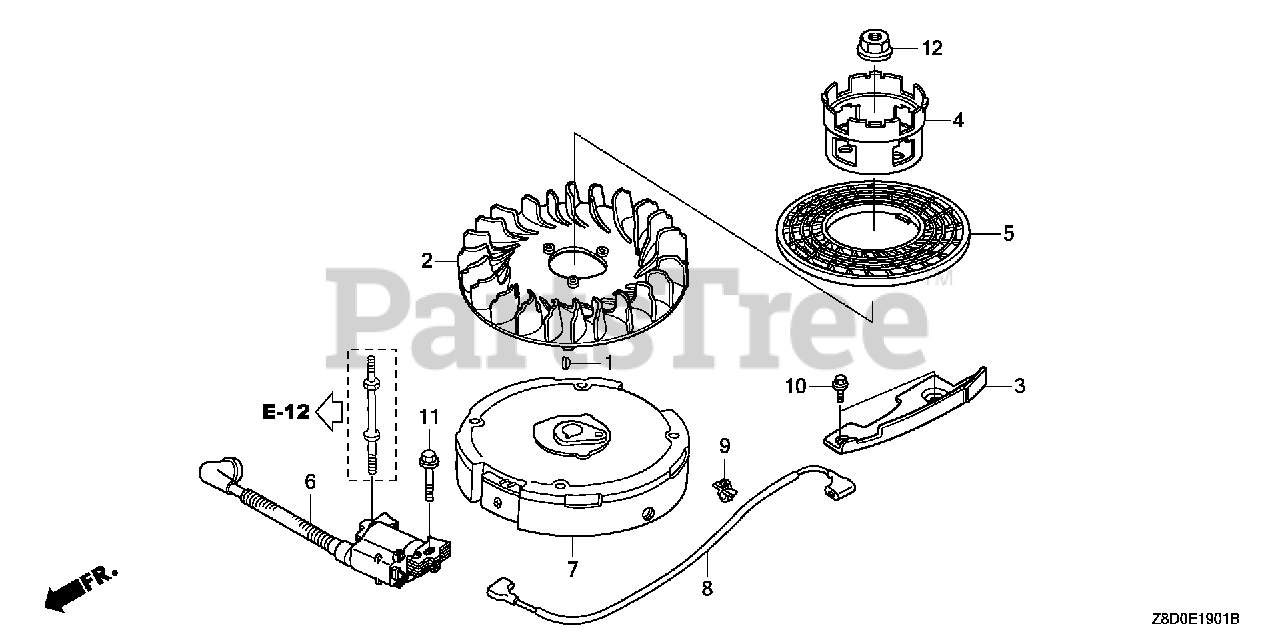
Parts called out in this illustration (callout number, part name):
1	KEY, SPECIAL WOODRUFF (25X18)
2	FAN, COOLING
3	PLATE, SIDE
4	PULLEY, STARTER
6	COIL ASSY., IGNITION (PHELON)
9	HOLDER, WIRE (FASTEX)
10	BOLT, FLANGE (6X12) (CT200)
11	BOLT, FLANGE (6X23)
12	NUT, SPECIAL (14MM)
